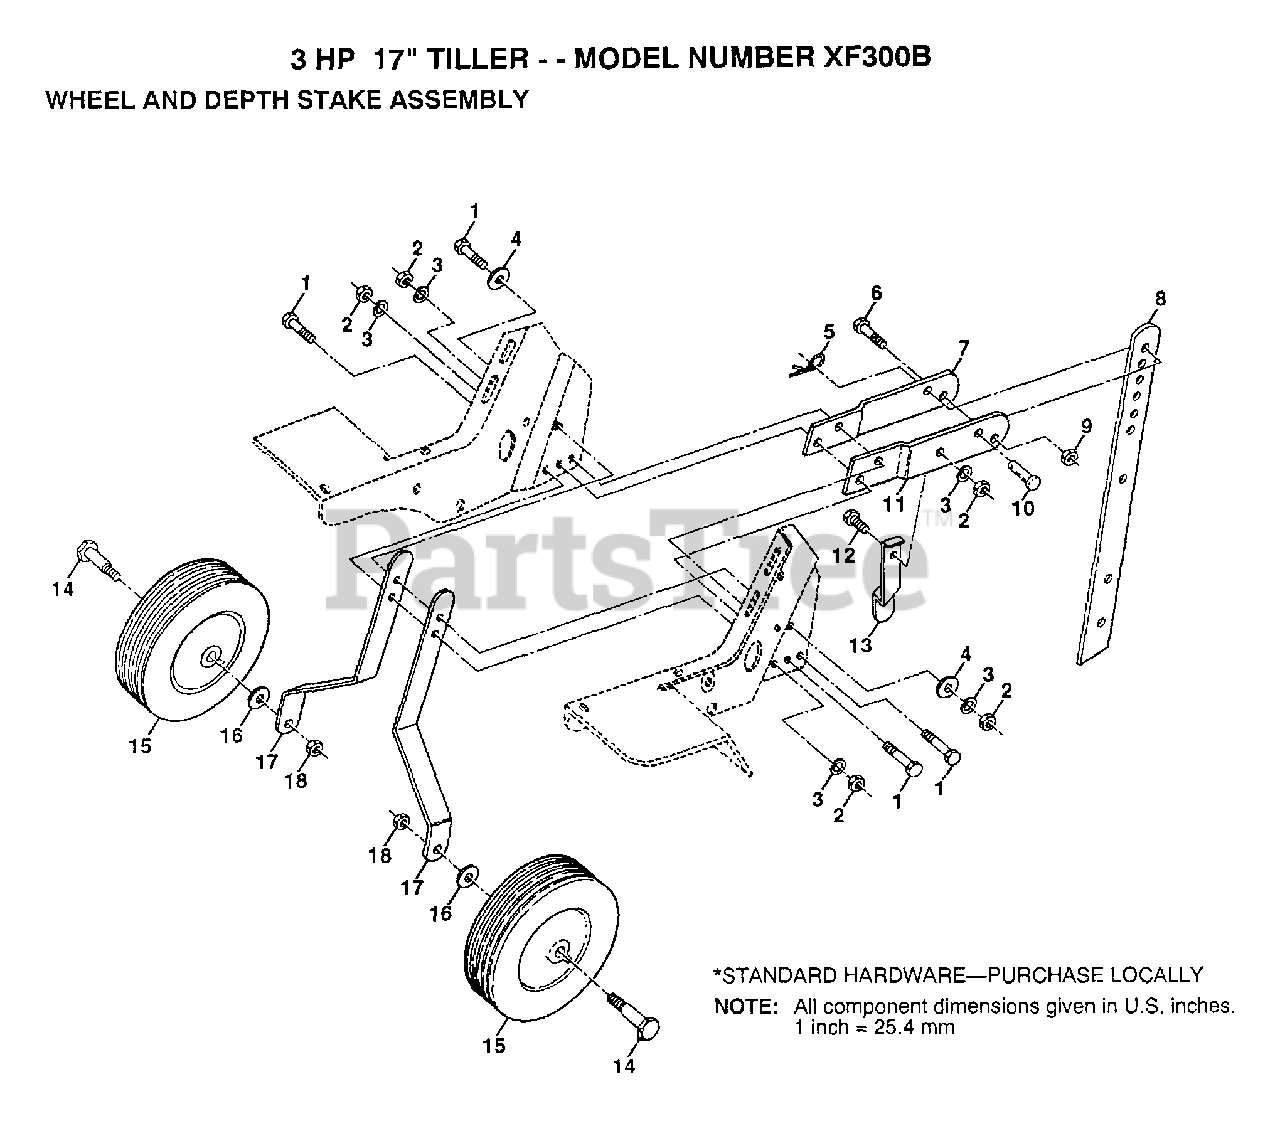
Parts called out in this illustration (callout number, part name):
2	NUT.HEX.5/16-18
3	LOCKWASHER
4	WASHER
5	SPRING.RETAINER
6	BOLT.3/8-24X1-1/2
7	STAKE.SUPT.TILLER
9	GRIPCO NUT
10	DRILLED RIVET RT
12	BOLT
13	STAKE SPRING CT
14	BOLT SHOULDER
16	WASHER
